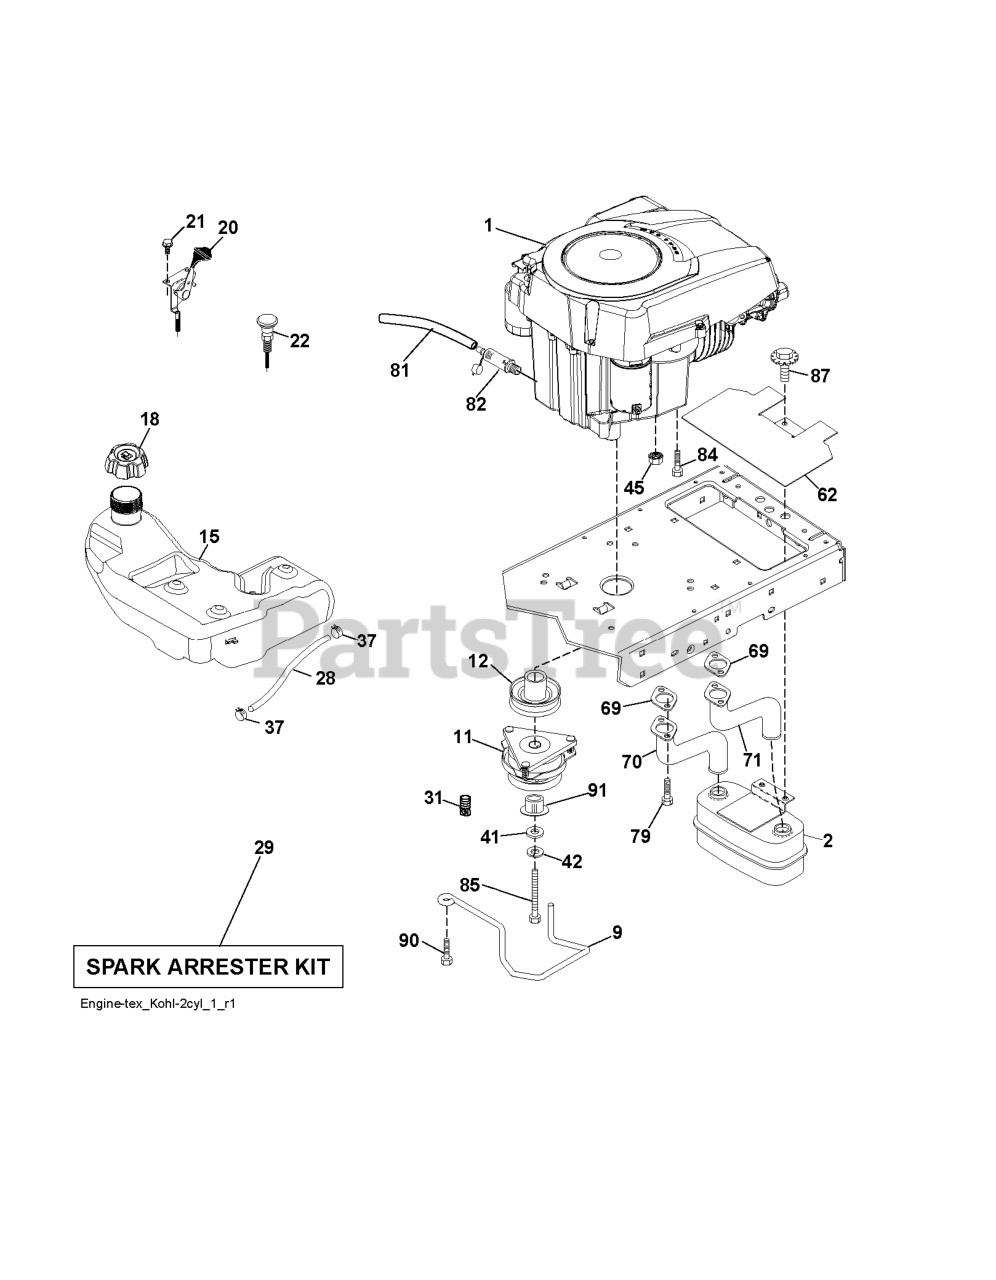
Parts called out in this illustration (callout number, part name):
2	MUFFLER.TWIN.CYL.LOW.TONE
9	KEEPER.BELT.ENGINE.4.2
11	CLUTCH MZ ZTR GT.48/54"1.125"
12	PULLEY ENGINE
15	TANK.FUEL.4GAL
18	CAP.FUEL.TANK.3"GREY
20	THROTTLE CONTROL
21	SCREW
22	CONTROL.CHOKE.ERGO.PUSH-IN.BLA
28	REPL BY 532 00 85-43
29	KIT.SPARK ARRESTOR 794945 B&S
37	HOSE CLAMP
42	LOCKWASHER
45	NUT
62	RP SHIELD HEAT MUFFLER
69	GASKET.EXHAUST.KOHL.CV18-CV26
70	RP.PIPE-EXHAUST LH
71	RP.PIPE-EXHAUST RH
81	TUBE, DRAIN OIL ASM.
82	PLUG DRAIN OIL EASY
84	SCREW 3/8-16X1
85	BOLT HEX 7/16-20 X 3.75 GR. 5
87	BOLT.5/16-18UNCX3/4 W/SEMS.BLK
90	SCREW 3/8-16X1
91	BUSHING.1.375OD
95	SCREW.SOCKET HD.5/16-1
